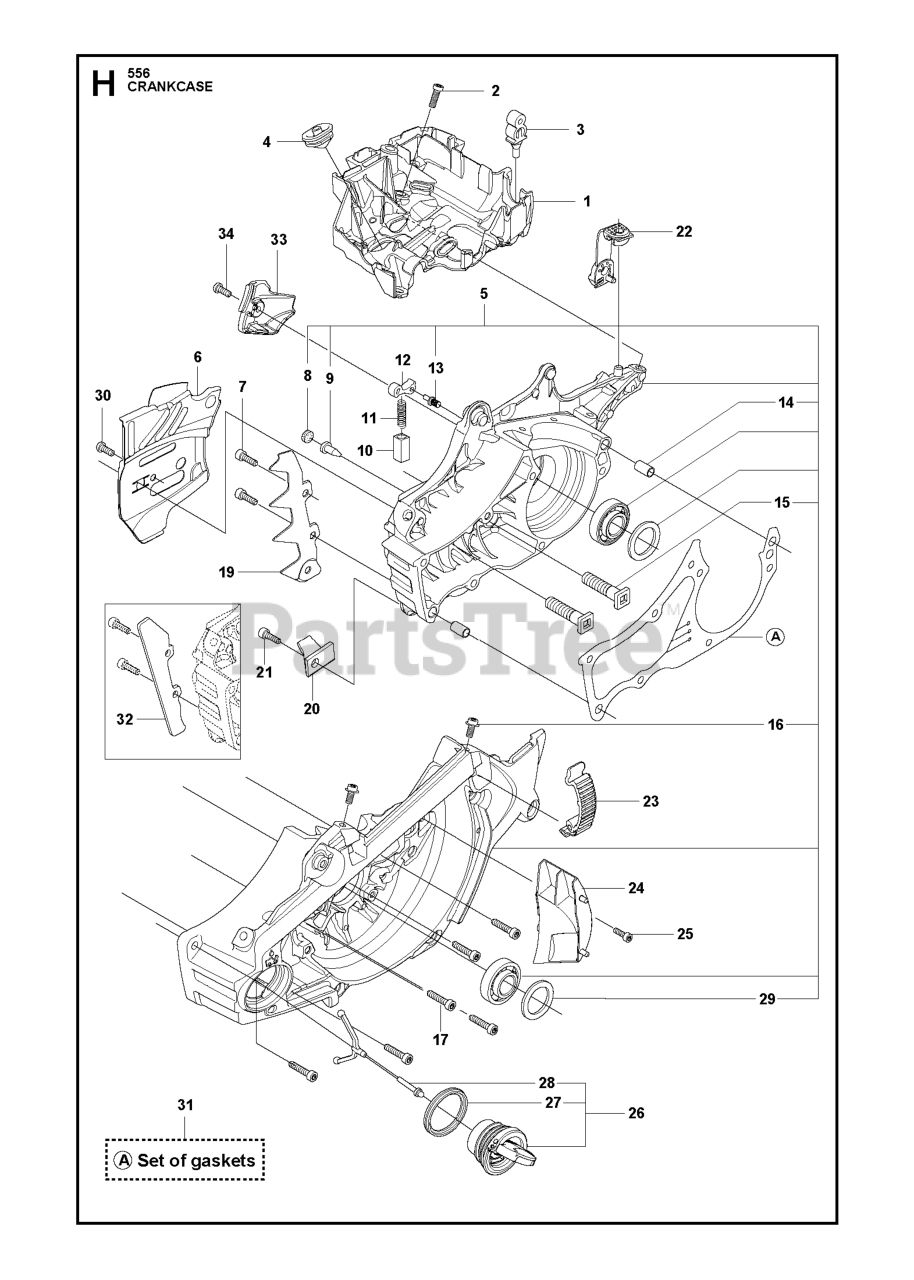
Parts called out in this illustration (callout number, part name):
2	APPLIQUE.BAGGER
3	1/4-20 U NUT
7	NUT T
10	FRAME TEX_CRD_GEN2 BAGGER FRAM
21	BAG FRAME BAGGER ASSEMBLY. HUS
25	LATCH LATCH. BAG. CRD GEN 2
26	SCREW HEX CRT
42	CLIP CHRISTMAS TREE CLIP
45	FRAME TEX_CRD_GEN2 UPPER U FRA
46	CONNECTOR RIGHT BAGGER CORNER
47	CONNECTOR LEFT BAGGER CORNER C
48	BAFFLE BAGGER SIDE CLOSE-OUT
49	BOLT, SHOULDER 5/16-18
50	BOLT.5/16-18UNCX3/4 W/SEMS.BLK
51	BOLT.CARR.SQNK.5/16-18UNC.X3/4
52	NUT.71038.31-18.HEX.NYLOCK
54	HANDLE BAGGER TOP FRONT HANDLE
55	BOLT
56	PIN.CLEVIS.183
58	RETAINER CLIP PM
59	TUBE BAGGER SPREADER TUBE, TEX
65	RETAINER M
69	SCREW,#8.FLAT.HEAD.DRILL.TIP
73	BOLT.CARRIAGE.5/16-18
79	SPACER.NYLON.75" X .4375
80	NUT LOCK HEX FLANGE 5/16-18
85	BRACKET.RH.PIVOT.ELE.DUMPX431
86	BRACKET.LH.PIVOT.ELE.DUMPX431
87	BRACKET.RH.MID.SUP.BAG.TEX.CRD
88	BRACKET.LH.MID.SUP.BAG.TEX.CRD
89	TUBE.WELD.OFSET.STRUT.BAG.X431
90	BRACKET.ELE.DUMP.ACT.BAG.X431
91	PIN.CLEVIS.(.375 X 1.25)
92	BRACKET.PNT.BAGGER.TOP.SUPPORT
93	BRACKET.PNT.RH.SUPPORT.ATTACH
94	BRACKET.PNT.LH.SUPPORT.ATTACH
95	SCREW
